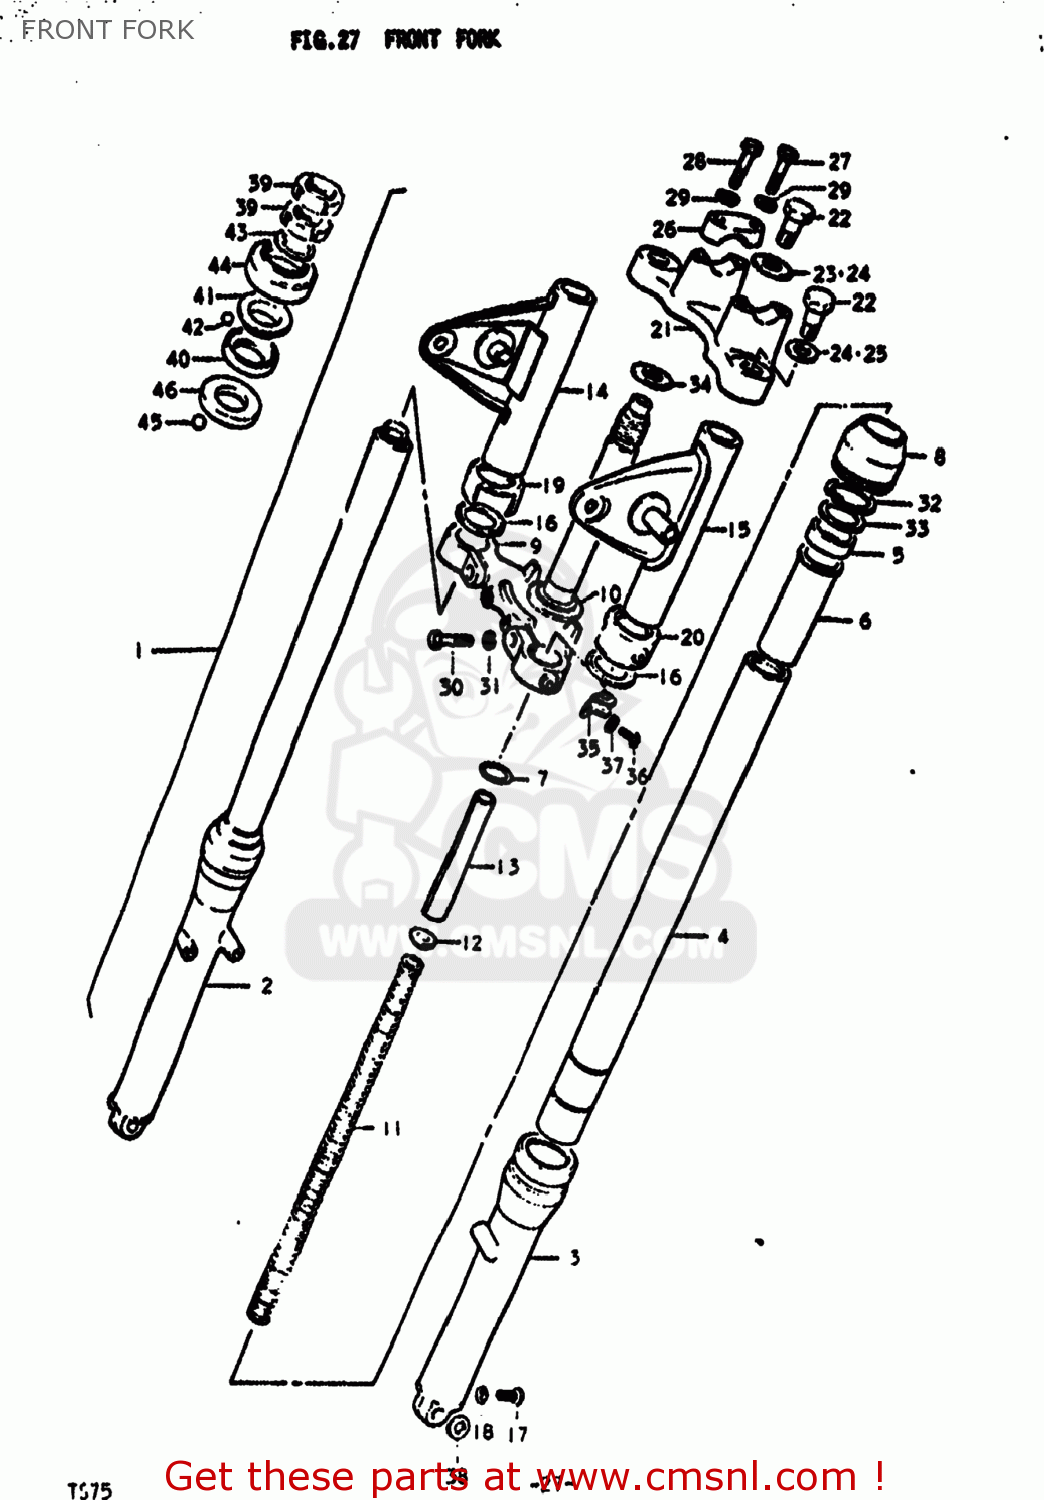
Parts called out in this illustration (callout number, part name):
1	DAMPER SET
2	TUBE,OUTER,RIGHT
3	TUBE,OUTER,LEFT
4	TUBE,FORK,INNER
5	OIL SEAL,FRONT FORK
6	GUIDE,FRONT FORK TUBE
7	O-RING,FORK INNER TUBE
8	SEAL,DUST
9	STEM,STEERING
10	RACE,STEERING OUTER LWR
11	SPRING
12	GUIDE,FRONT FORK SPRING C
13	SPACER,SPRING
14	BRACKET COMP,HEADLAMP
15	BRACKET,HEADLAMP,LEFT
16	CUSHION,HEADLAMP BRACKET
17	SCREW
18	GASKET,DRAIN,PLUG (NAS)
19	COVER STEM RH
20	COVER STEM LH
21	HEAD,STEERING STEM
22	BOLT,FORK INNER TUBE
23	WASHER
24	WASHER,STEM HEAD(10.5X30X3.2)
25	WASHER
26	HOLDER,HANDLEBAR
27	Bolt
28	BOLT
29	LOCK WASHER
30	BOLT,FORK INNER TUBE F
31	LOCK WASHER
32	CIRCLIP
33	RING,FORK BACK UP
34	WASHER,STEERING STEM L
35	CLIP,BRAKE CABLE
36	SCREW
37	LOCK WASHER
38	WASHER
39	NUT
40	RACE,STEERING INNER UPR
41	LACE,STEERING OUTER UPR
42	BALL
43	WASHER
44	DUST SEAL,STEERING UPR
45	BALL
46	LACE,STEERING INNER LWR
